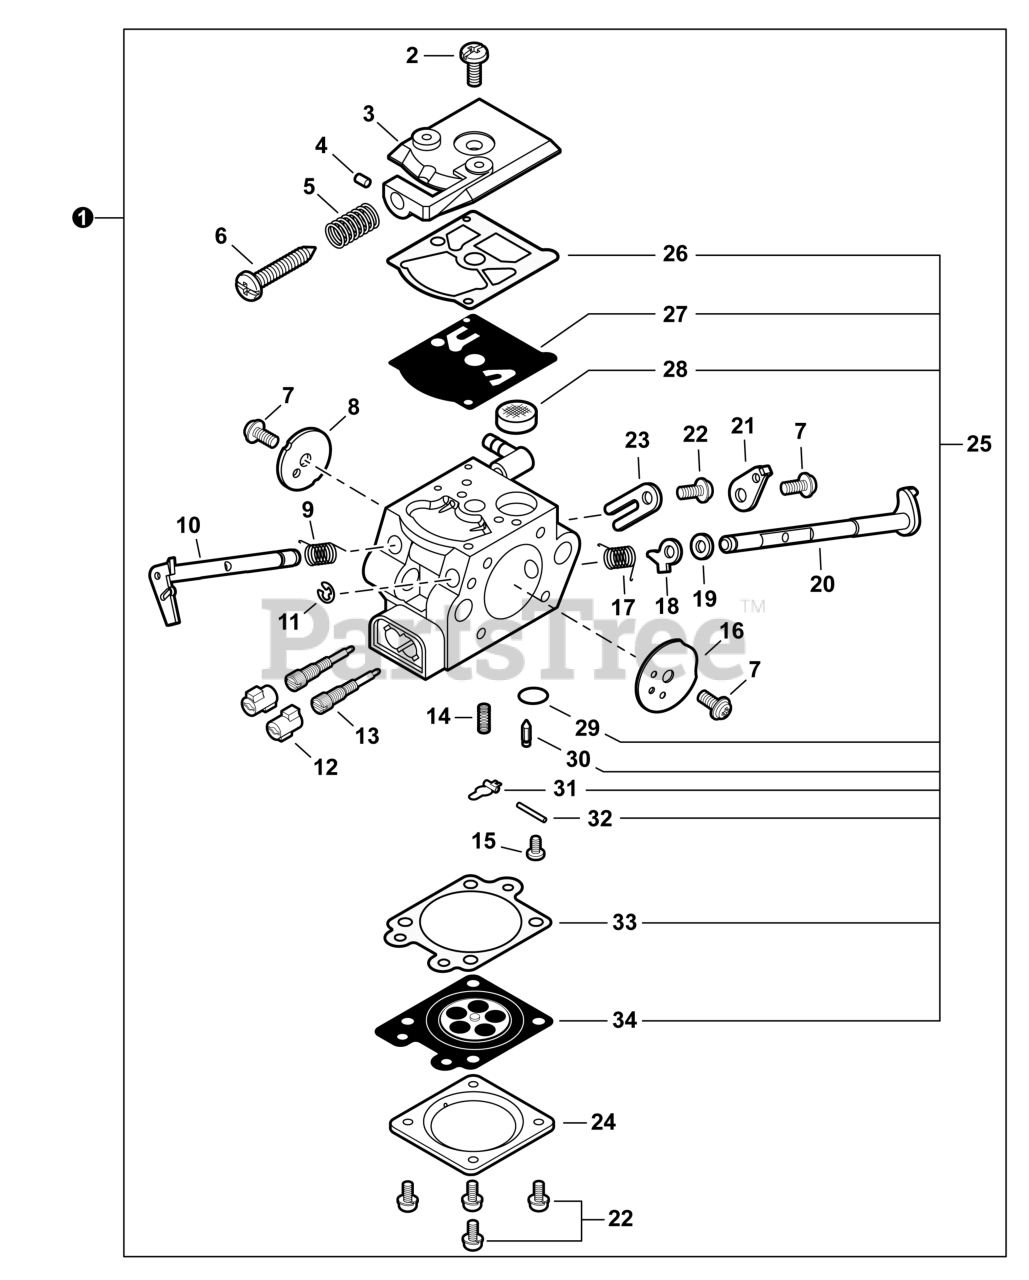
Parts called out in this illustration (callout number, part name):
1	CARBURETOR - WT-820
3	COVER, FUEL PUMP
4	PLUG, FRICTION
5	SPRING, IDLE ADJUST
6	SCREW, IDLE ADJUST
8	VALVE, THROTTLE
9	SPRING, THROTTLE RETURN
10	SHAFT, THROTTLE
12	CAP, LIMITER
13	NEEDLE, MIXTURE
14	SPRING, METERING LEVER
15	SCREW, METERING LEVER PIN
16	VALVE, CHOKE
17	SPRING, CHOKE RETURN
18	LEVER, FAST IDLE
20	SHAFT, CHOKE
21	LEVER, THROTTLE
23	CLIP, THROTTLE SHAFT
24	COVER, METERING DIAPHRAGM
25	REPAIR KIT, CARBURETOR
26	GASKET, FUEL PUMP
27	DIAPHRAGM, PUMP
28	SCREEN, FUEL INLET
29	PLUG, WELCH
30	VALVE, INLET NEEDLE
31	LEVER, METERING
32	PIN, METERING LEVER
33	GASKET, METERING DIAPHRAGM
34	DIAPHRAGM, METERING
